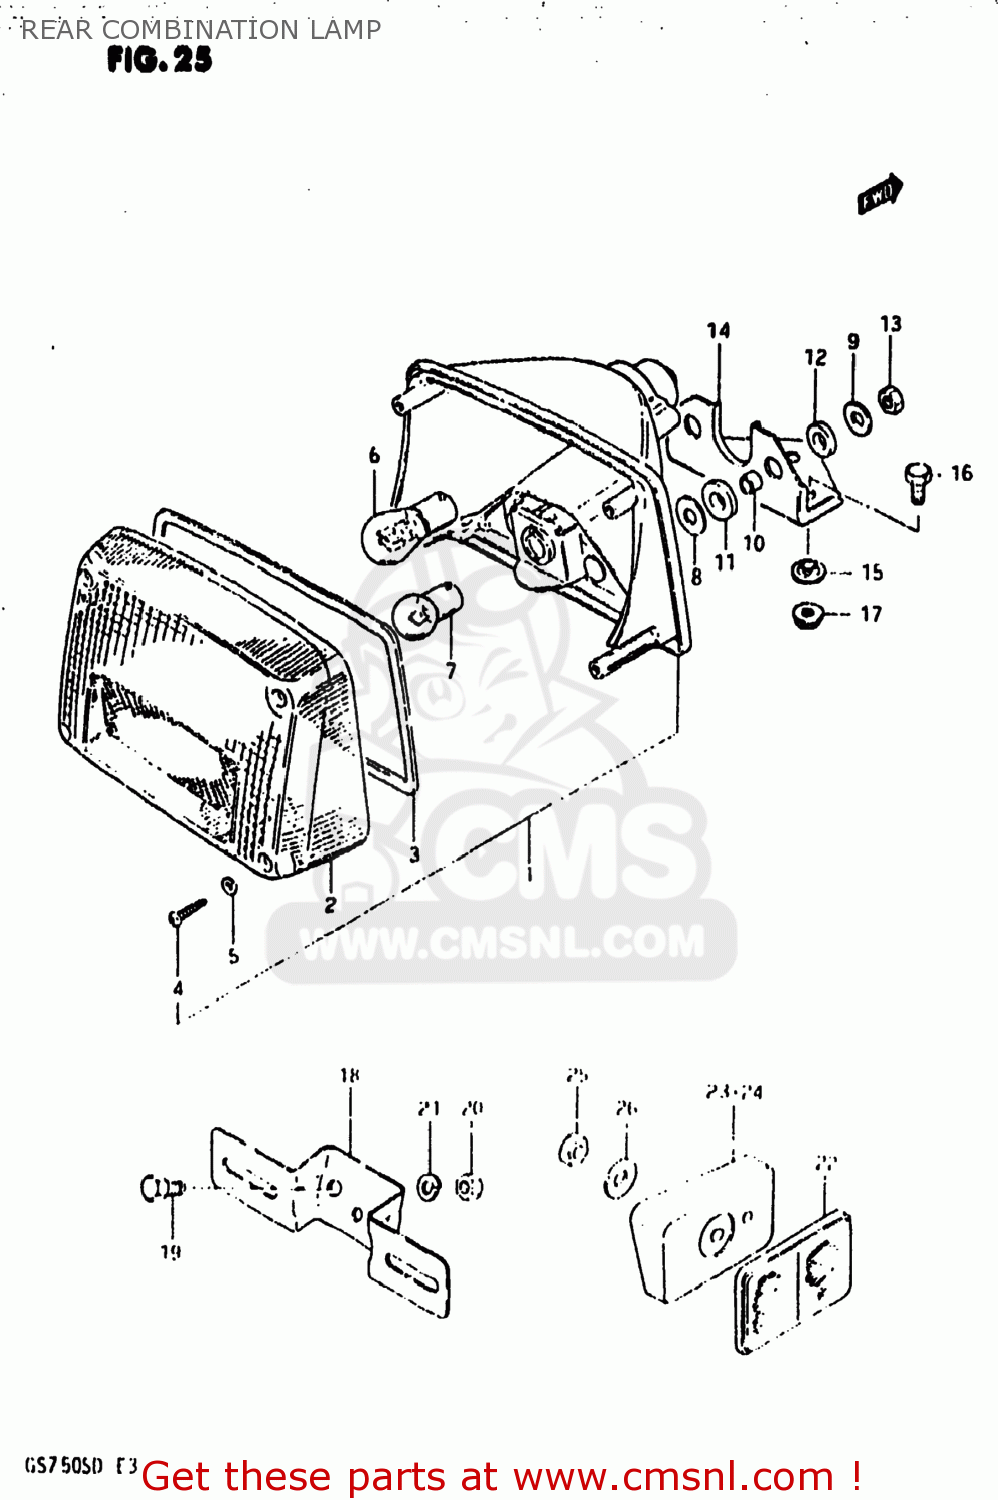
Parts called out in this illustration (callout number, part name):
1	LAMP ASSY,RR COMBINATION
2	LENS
3	GASKET (NAS)
4	SCREW,REAR COMBINATION LAMP
5	GASKET (NAS)
6	BULB(12V23W)
7	BULB
8	WASHER
9	WASHER(6,5X22X1.6)
10	SPACER(6.1X9X7.5)
11	CUSHION
12	CUSHION
13	NUT 6MM
14	BRACKET,REAR COMBINATION LAMP
15	WASHER
16	BOLT, UPPER
17	NUT 6MM
18	BRACKET,LICENSE PLATE
19	BOLT
20	NUT
21	LOCK WASHER
22	REFLEX REFLECTOR,RR
23	SPACER,REAR REFLEX REFLECTOR
24	SPACER,REAR REFLEX REFLECTOR
25	NUT
26	WASHER
